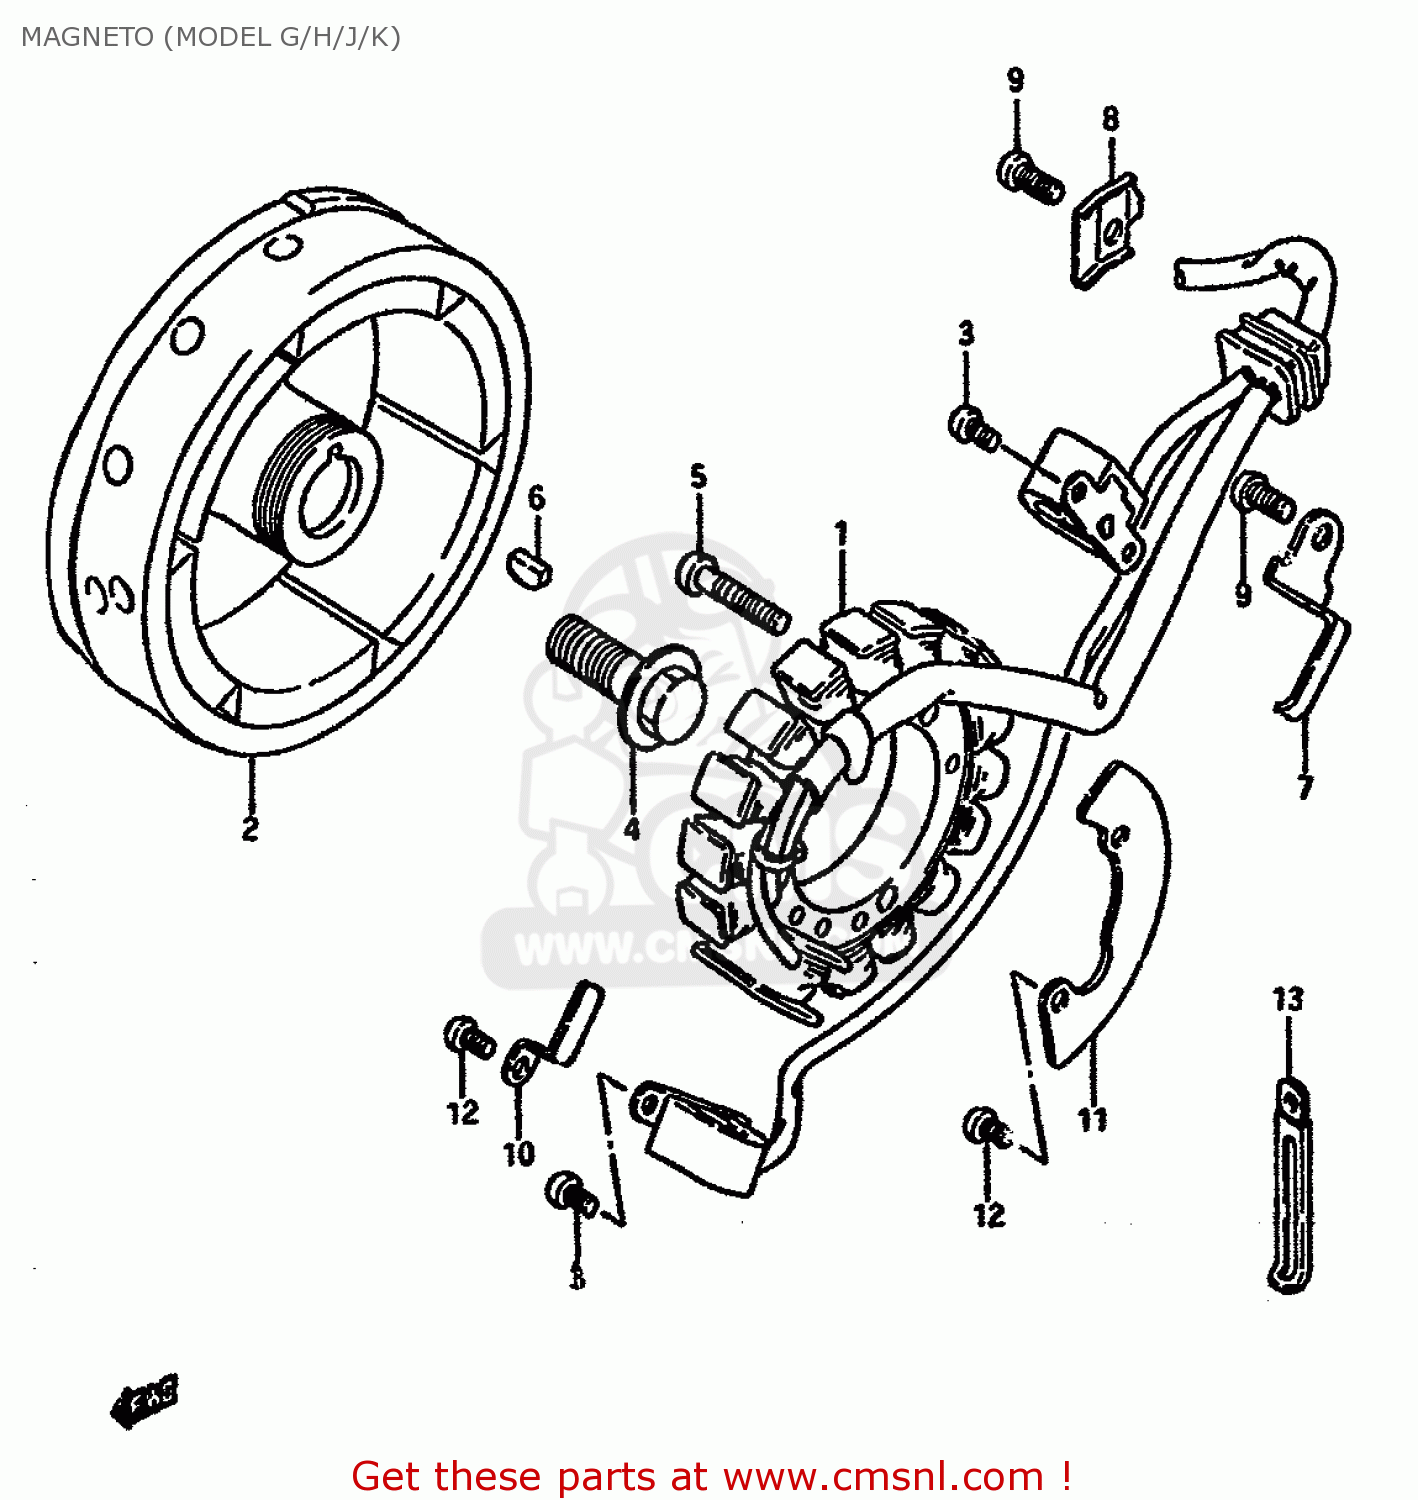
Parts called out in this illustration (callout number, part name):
1	STATOR ASSY
2	ROTOR,FLYWHEEL
3	SCREW
4	BOLT(14X43)
5	SCREW 6X30
6	KEY 4MM
7	CLAMP,MAGNETO LEAD WIRE
8	CLAMP,MAGNETO LEAD WIRE
9	SCREW
10	CLAMP
11	CLAMP
12	SCREW
13	CLAMP
